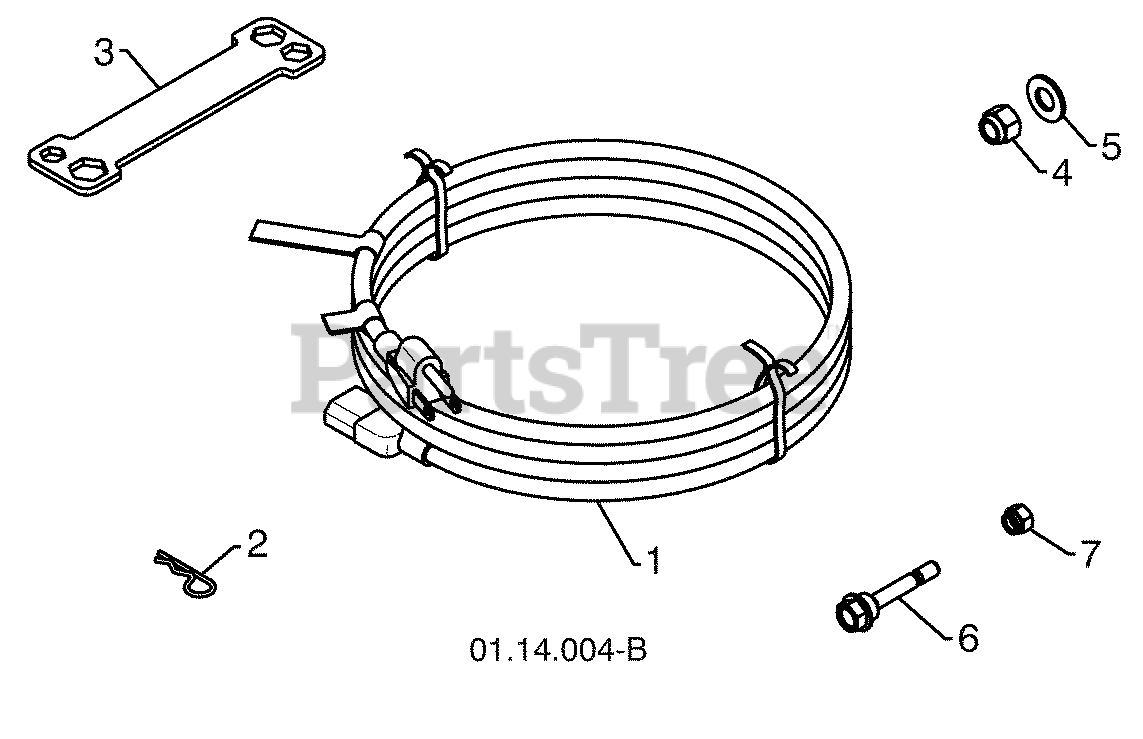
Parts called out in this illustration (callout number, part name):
1	POWER CORD
2	RETAINER PIN
4	LOCKNUT 3/8-16
5	WASHER 3/8
6	SHEAR BOLT 1/4-20 X 1-3/4
7	LOCKNUT 1/4-20
